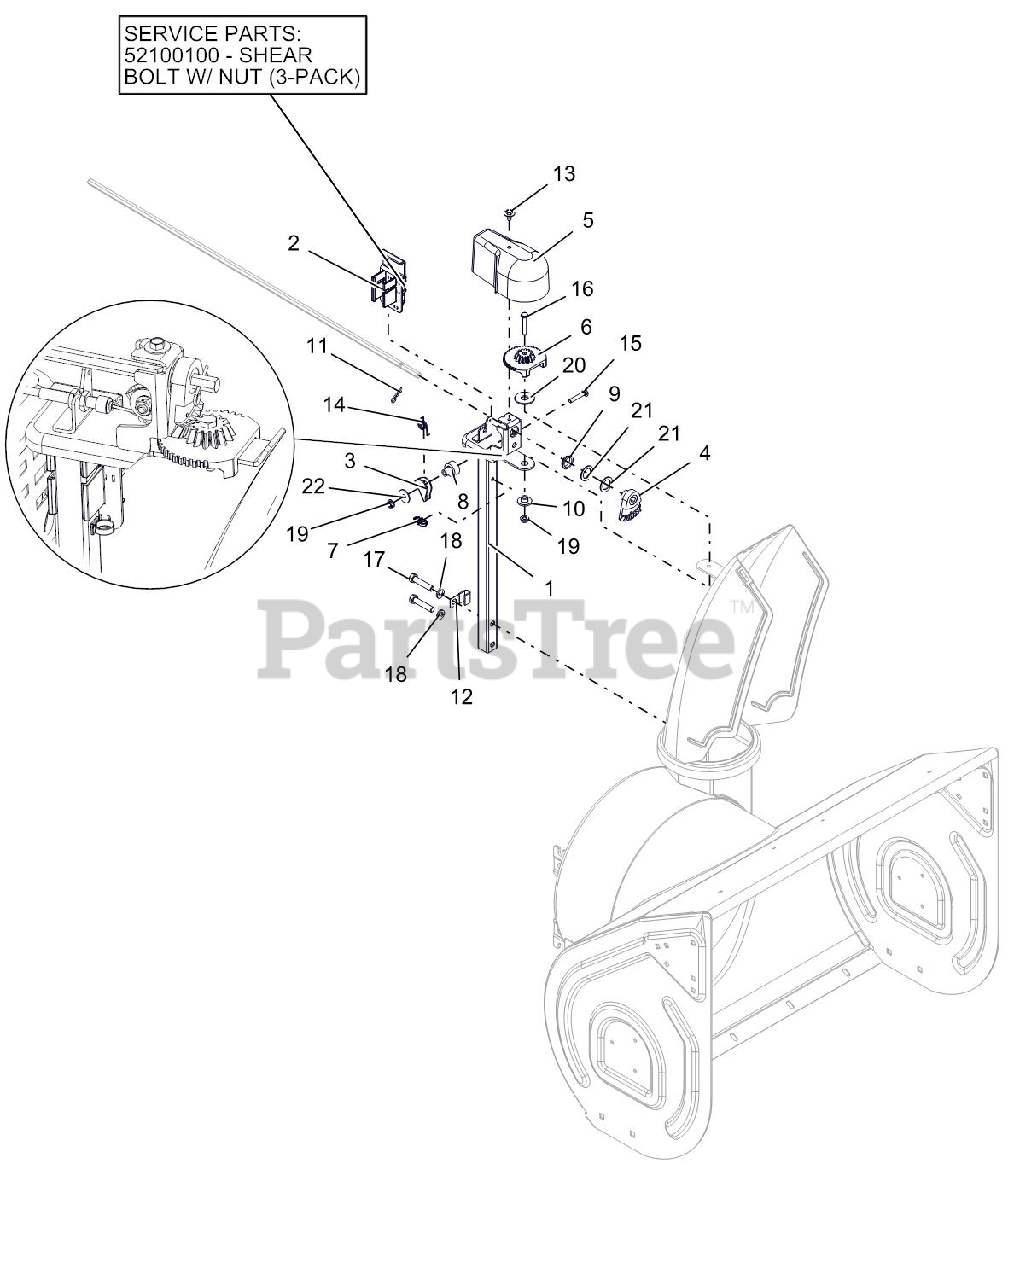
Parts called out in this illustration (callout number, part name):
1	PEDESTAL, CHUTE - QUICK STICK
2	SHEAR BOLT SERVICE ASSEMBLY
2	HOLDER W LARGE SHEAR BOLT /NUT
3	ARM, LOCKING
4	GEAR, CHUTE-ACTUATION
5	COVER, CHUTE GEAR
6	GEAR, CHUTE
7	CLIP, CABLE GUIDE
8	BUSHING, LOCK ARM
9	BUSHING, POLYLINER-.75 SNAPIN
10	BSHG-FLG .265X.477X.375X1.00
11	PIN-HAIR INT .08X.18X1.18 YWZC
12	J-CLAMP
13	SCR-TAP .25-20X.50 LGHWH TR YZ
14	SG-TORS
15	@BLT-RDHDSQNK .25-20X1.50 G5YZ
16	@BLT-HEX .25-20X1.50 GR5 YWZC
17	@BLT-HEX .38-16X1.75 GR5 YWZC
18	@WSHR-LK .38X.094 REG YWZC
19	@NUT-LK-CTR-FLG .25-20 YWZC
20	WSHR-FLT-NYL .515X1.375X.093
21	WSHR-FL-STL.754X1.125X.062YWZC
22	WSHR-FL-STL .281X1.000X.063
